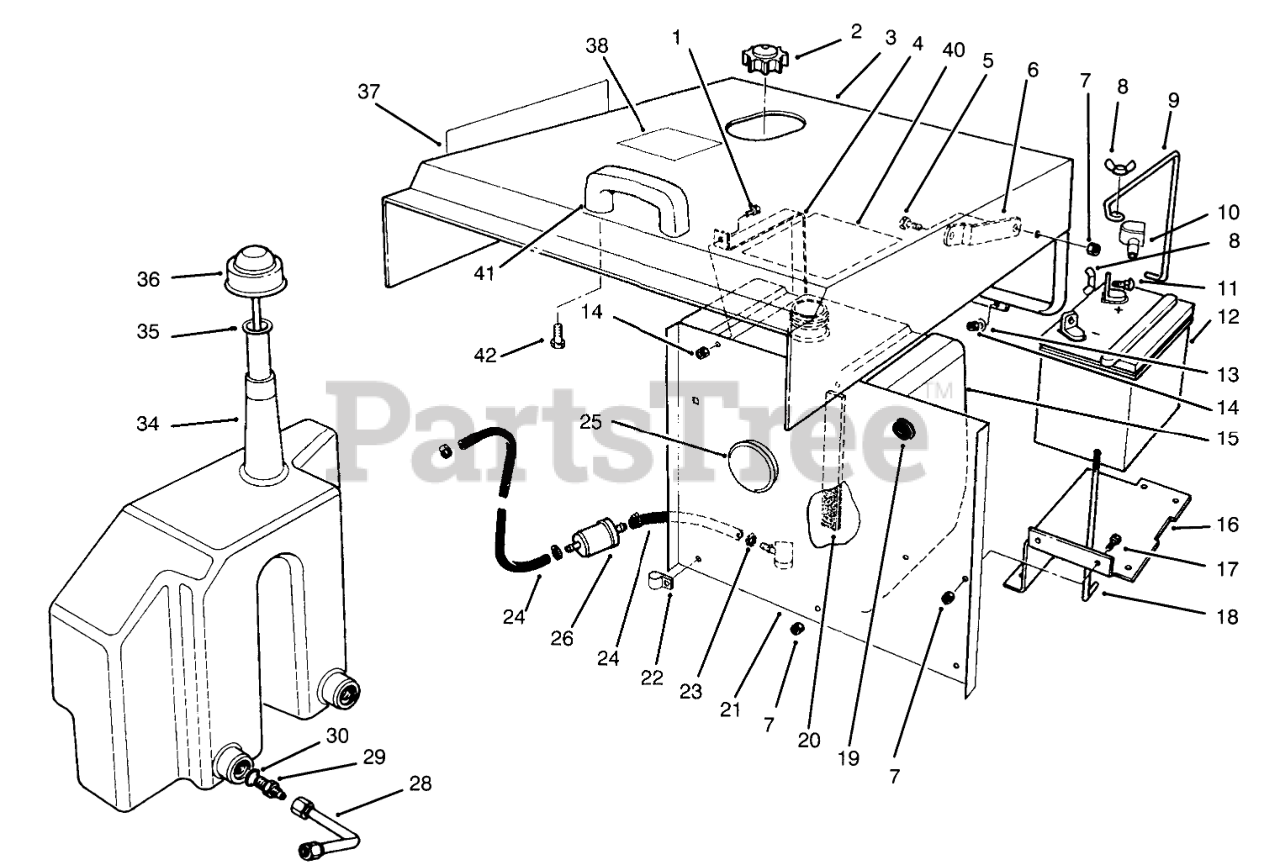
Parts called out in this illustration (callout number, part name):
1	SCREW-HH
2	GAS CAP ASM
3	HOOD-118 - SERVICE
4	Strap-Fuel Tank
5	SCREW-HH
6	UPPER HOOD STOP
7	NUT-LOCK, NI
8	NUT-WING
9	BATTERY CLAMP
10	BOOT-TERMINAL, RED
11	BOLT-CARR
12	Battery
13	WASHER-FLAT
14	NUT-LOCK, NI
15	TANK-FUEL
16	Support-Battery
17	SCREW-HH
18	ROD-SUPPORT, BATTERY
19	GROMMET
20	TANK SPONGE
21	Shield-Heat
23	CLAMP-WORM
24	GAS HOSE
25	PLUG BUTTON CAP
26	FUEL FILTER
28	TUBE ASM
29	Fitting-Hydraulic Straight(Incl Ref. #30)
30	"O"Ring
34	OIL RESERVOIR
35	SCREEN-FILLER
36	CAP WA
37	Decal-ProLine 120
38	DECAL - CAUTION FUEL
40	DECAL - SERVICE PL120
41	HANDLE-DOOR
42	SCREW-HWH
